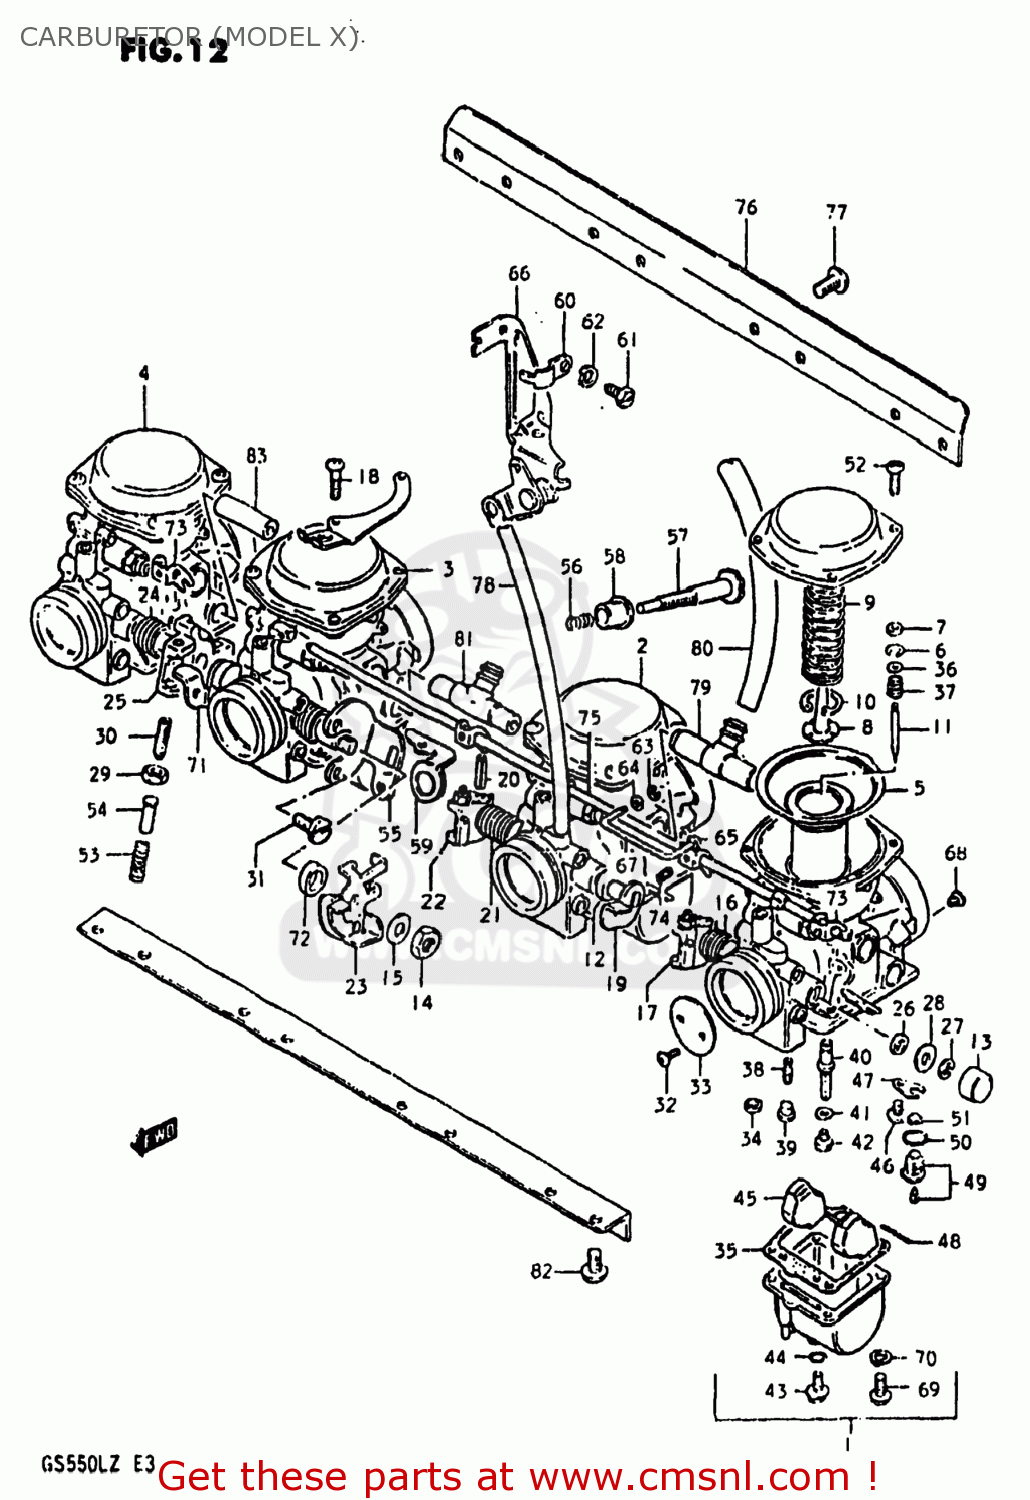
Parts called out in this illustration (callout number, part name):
1	CARBURETOR ASSEMBLY,NO.1 (A
2	CARBURETOR ASSEMBLY
3	CARBURETOR ASSEMBLY
4	CARBURETOR ASSEMBLY
5	DIAPHRAGM ASSEMBLY
6	CLIP,NEEDLE
7	RING
8	HOLDER,GUIDE
9	SPRING
10	E RING
11	NEEDLE JET
12	GASKET,THROTTLE SHAFT (NAS)
13	CAP
14	NUT
15	NUT
16	SPRING,THROTTLE SHAFT
17	SHAFT,THROTTLE
18	SCREW
19	SHAFT,THROTTLE
20	PIN,THROTTLE SHAFT
21	SPRING,THROTTLE SHAFT
22	LEVER,THROTTLE SHAFT
23	LEVER ASSEMBLY,THROTTLE
24	SPRING,THROTTLE SHAFT
25	SHAFT,THROTTLE
26	SEAL
27	E RING
28	GASKET,THROTTLE SHAFT (NAS)
29	NUT
30	SCREW
31	SCREW,THROTTLE ADJUST B
32	SCREW
33	VALVE,THROTTLE
34	GASKET (NAS)
35	GASKET,FLOAT CHAMBER (NAS)
36	WASHER
37	SPRING
38	JET,PILOT
39	PLUG,NEEDLE JET
40	JET,NEEDLE
41	WASHER,NEEDLE NOZZLE
42	JET,MAIN(92.5)
43	PLUG,DRAIN
44	GASKET (NAS)
45	FLOAT
46	SCREW
47	PLATE
48	PIN,FLOAT
49	VALVE ASSEMBLY,NEEDLE
50	O-RING,NEEDLE VALVE
51	FILTER
52	SCREW
53	SPRING,THROTTLE SCREW
54	PIN,THROTTLE LEVER
55	BRACKET,THROTTLE ADJUST
56	SPRING
57	SCREW
58	BUSH
59	BRACKET,THROTTLE ADJUST
60	BRACKET,STARTER
61	BOLT
62	LOCK WASHER
63	CAP,LEVER
64	SEAT,SPRING
65	LEVER ASSY
66	BRACKET
67	ROD,STARTER LEVER
68	JET,AIR(150)
69	SCREW
70	LOCK WASHER
71	SHAFT,THROTTLE
72	WASHER
73	LEVER
74	SCREW
75	SHAFT,STARTER
76	BRACKET
77	SCREW
78	HOSE
79	NIPPLE
80	HOSE
81	NIPPLE,CARBURETOR
82	SCREW 6X12
83	NIPPLE
